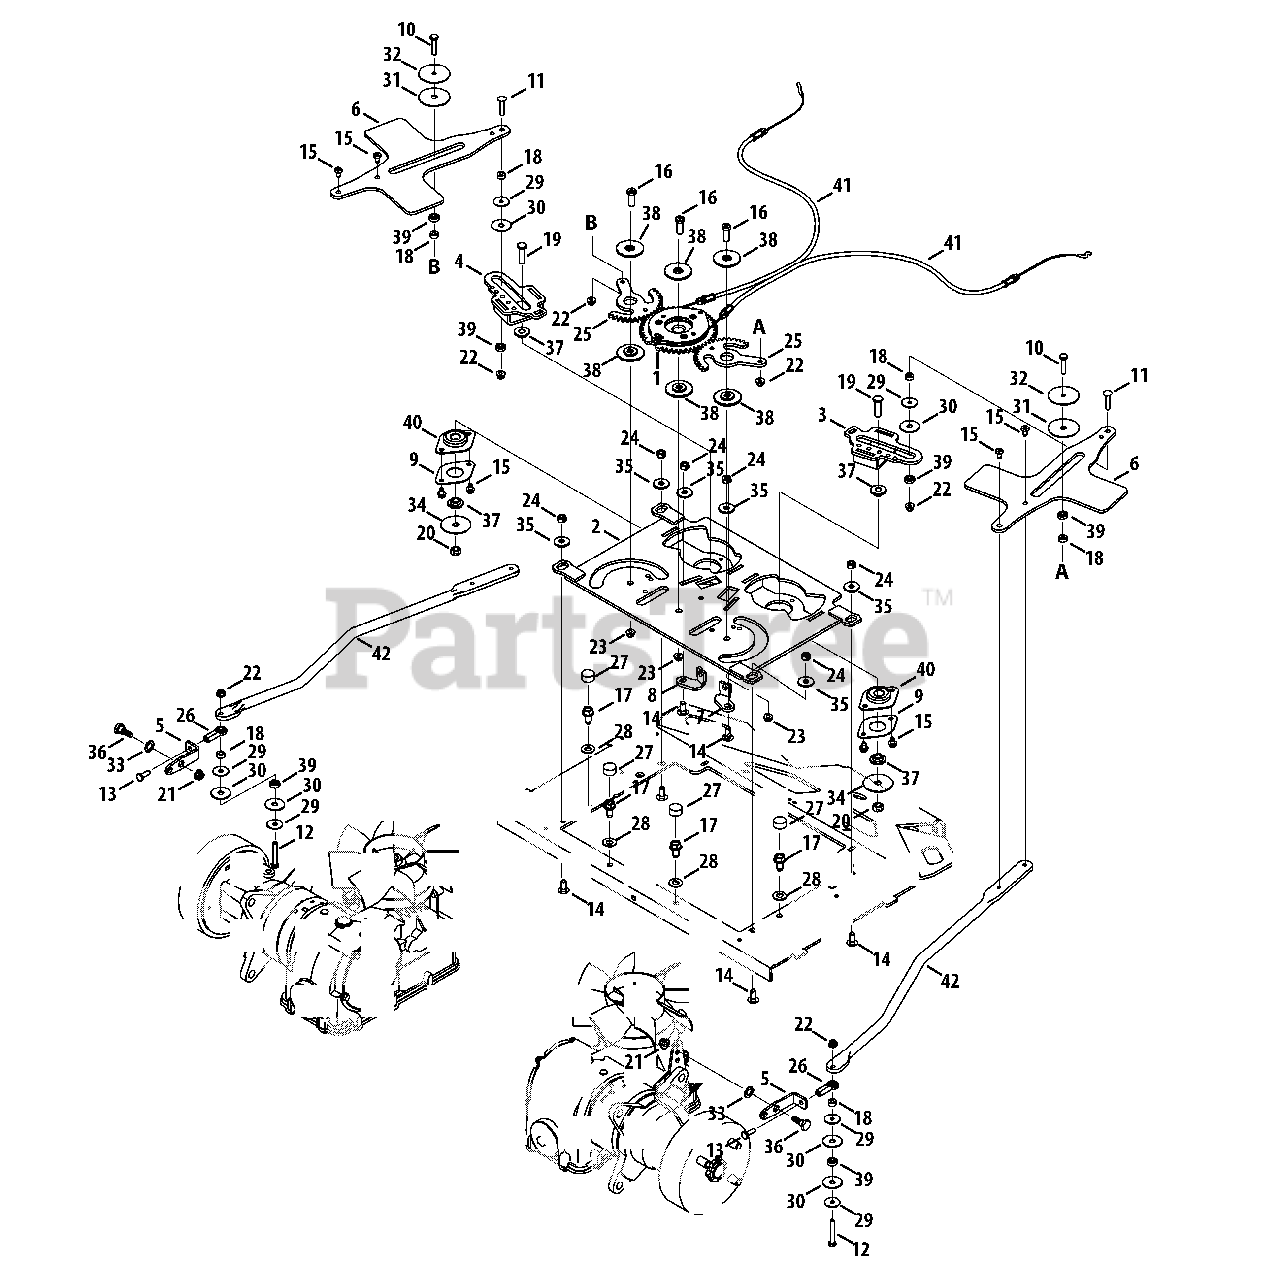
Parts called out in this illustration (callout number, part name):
1	Pump Control Gear
3	Pump Control Cam Assembly, RH
4	Pump Control Cam Assembly, LH
5	Pump Control Bracket
6	Pump Steering Arm Actuator
7	Steering Cable Bracket
8	Steering Cable Bracket
9	Retainer Bearing Plate
10	Hex Cap Screw, 1/4-20 x 1.25
11	Carriage Screw, 1/4-20 x 1.25
12	Hex Cap Screw, 1/4-20 x 1.75
13	Hex Cap Screw, 1/4-28 x .75
14	Carriage Bolt, 5/16-18 x .75
15	Hex Flange Screw, 1/4-20 x .500
16	Socket Head Screw, 3/8-16 x 1.00
17	Screw, 3/8-16 x .75
18	Spacer, .256 x .500 x .240
19	Hex Cap Screw, 3/8-16 x 1.25
20	Nut, 3/8-16, Hexlock
21	Nut, 5/16-18, Flangelock
22	Nut, 1/4-20, Flangelock
23	Nut, 3/8-16, Flnagelock
24	Nut, 5/16-18, Hexlock
25	Yoke Steering Gear
26	Rod End, 1/4-28
27	Slide Cap
28	Washer, .406 x .875 x .059
29	Washer, .255 x 1.00 x .060
30	Washer, .355 x 1.25 x .060
31	Washer, .356 x 2.00 x .060
32	Washer, .260 x 2.00 x .060
33	Washer, .469 x .75 x .060
34	Washer, .406 x 1.92 x .060
35	Washer, .345 x 1.00 x .100
36	Shoulder Screw, .437 x .268, 5/16-18
37	Shoulder Spacer, .38 x 1.00 x .31
38	Shoulder Spacer, .853 x .385 x .100
39	Ball Bearing, .250 x .625
40	Ball Bearing, .625
41	Transmission Link Control Cable
42	Pump Control Rod
